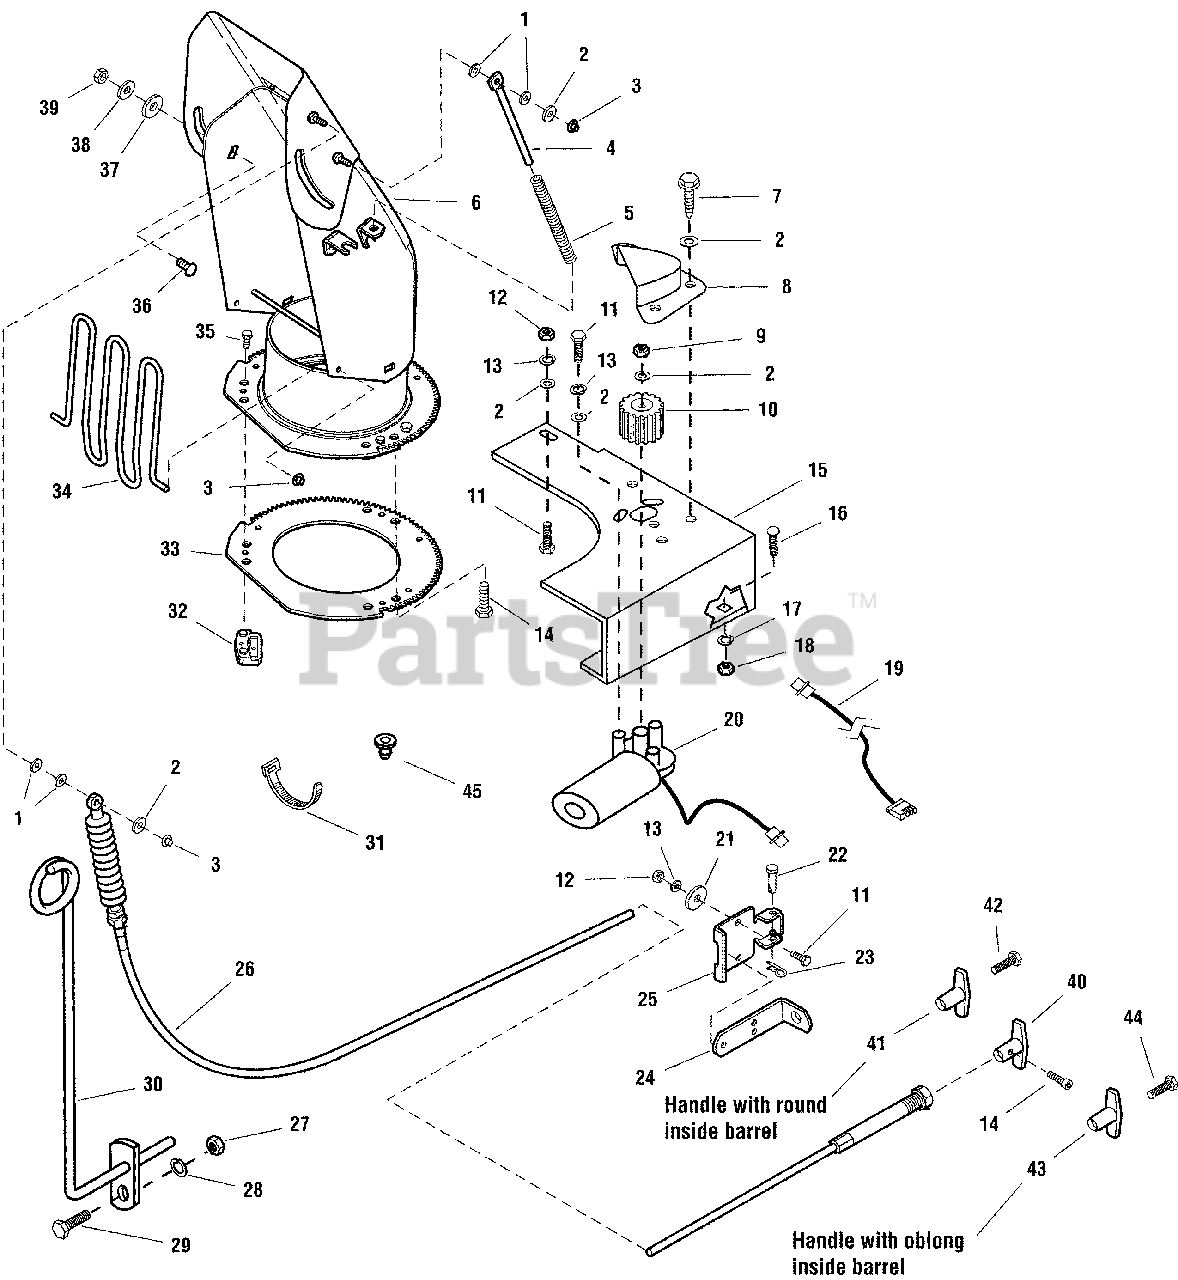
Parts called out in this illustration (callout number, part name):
2	WASHER,1/4
3	NUT, Push, 1/4
6	CHUTE & DEFLECTOR ASSEMBLY
7	SCREW, Hex Head, Taptite, 1/4-20 x 1/2
8	COVER, Pinion
9	NUT, Hex, Centerlock, 1/4-20
10	PINION, 15 Teeth
11	CAPSCREW, Hex Head, 1/4-20 x 7/8
12	NUT, Hex, 1/4-20
13	LOCKWASHER, 1/4
14	SCREW, Set Hex #10-24 x 3/8
15	SUPPORT, Motor
16	CARRIAGE BOLT, 3/8-16 x 3/4
17	LOCKWASHER,3/8
18	NUT, Hex 3/8-16
19	HARNESS ASSEMBLY
20	MOTOR, Eletric
21	WASHER, 1/4
22	PIN, Flat Head Drilled
23	CLIP, Hair Pin
26	CABLE & KNOB ASSEMBLY
27	NUT, Hex, 5/16-18
28	LOCKWASHER, 5/16
29	CAPSCREW, Hex Head, 5/16-18 x 1
30	ROD & BAR ASSEMBLY
34	GUARD & SUPPORT ASSEMBLY
35	SCREW, Hex Head Taptite 10-14 x 5/8
36	CARRIAGE BOLT, 5/16-18 x 3/4
38	WASHER, 5/16
39	NUT, Hex Lock ESNA 5/16-18
41	HANDLE "T"
42	SCREW, Round Head
43	HANDLE "T"
44	SCREW, #8c x 3/4
45	CAP, Plug Black Poly
